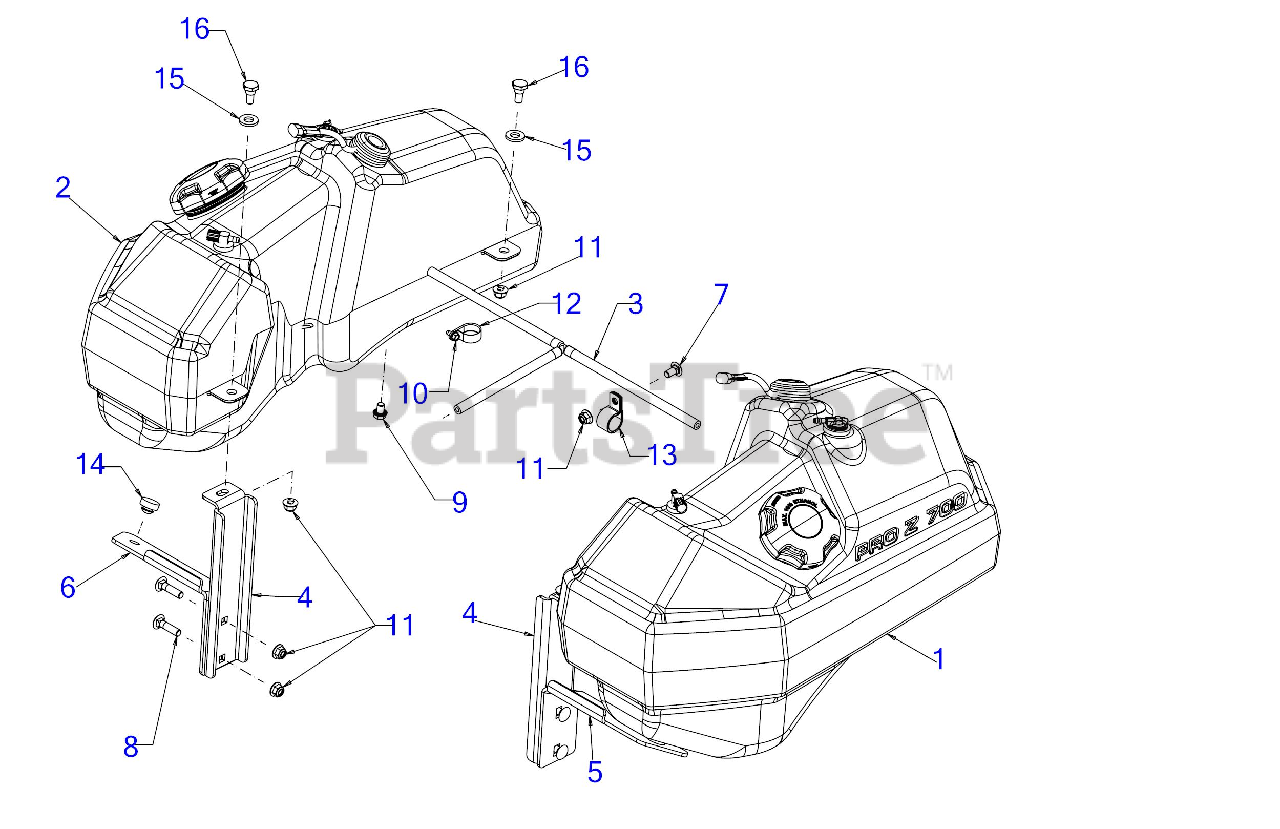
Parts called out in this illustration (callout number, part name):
1	FUEL TANK ASSEMBLY (RH) (7.25 GAL)
2	FUEL TANK ASSEMBLY (LH) (7.25 GAL)
3	FUEL LINE ASSEMBLY
7	CARRIAGE BOLT 3/8-16 x .750 GR5
8	CARRIAGE BOLT 3/8-16 x 1.50
9	SCREW 3/8-16 x .500 GR5
10	SCREW 1/4-20 X.500
12	DRAIN HOSE CLAMP
13	HOSE CLAMP 1.0"
14	RUBBER BUMPER 1.000 x .313
15	FLAT WASHER .510 x 1.000 x .125
16	SHOULDER SCREW .498 DIA x .340
